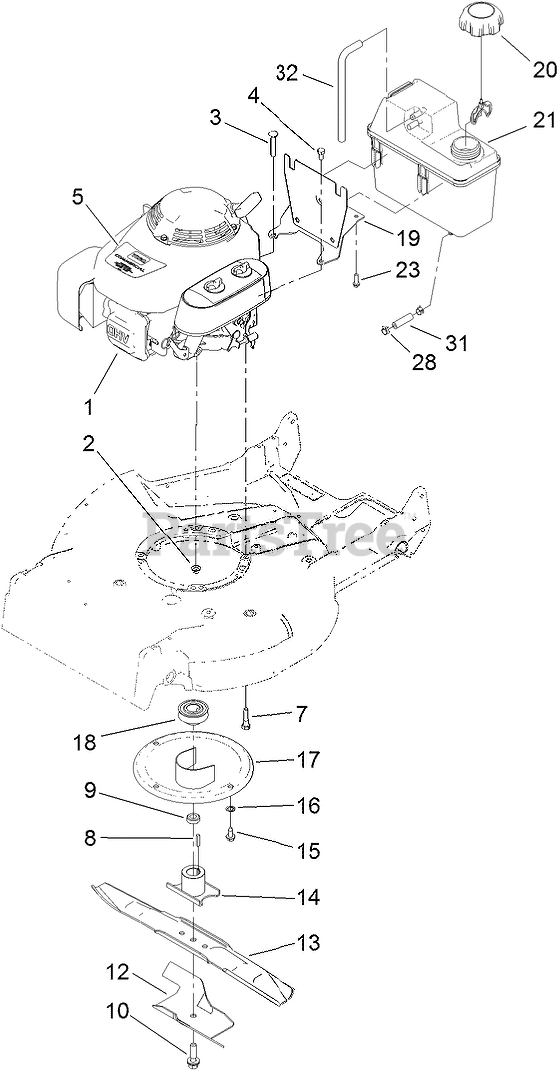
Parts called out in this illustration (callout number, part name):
2	NUT-HF
3	Screw-CARR
4	SCREW-HH
5	DECAL-ENGINE, HONDA
7	SCREW-SHOULDER
8	KEY-SQUARE
9	Spacer-Retainer, Blade
10	BOLT-BLADE
12	STIFFENER-BLADE
13	BLADE-21 INCH
14	RETAINER-BLADE
15	SCREW-HWHTF
16	WASHER-LOCK, INTERNAL
17	CRANKSHAFT PROTECTOR ASM
18	PULLEY-DRIVER
19	MOUNT-TANK
20	CAP-RATCHET, TETHERED
21	TANK-FUEL
23	SCREW-HWH
28	CLAMP-HOSE
31	HOSE-FUEL
32	HOSE-VENT, CANISTER
